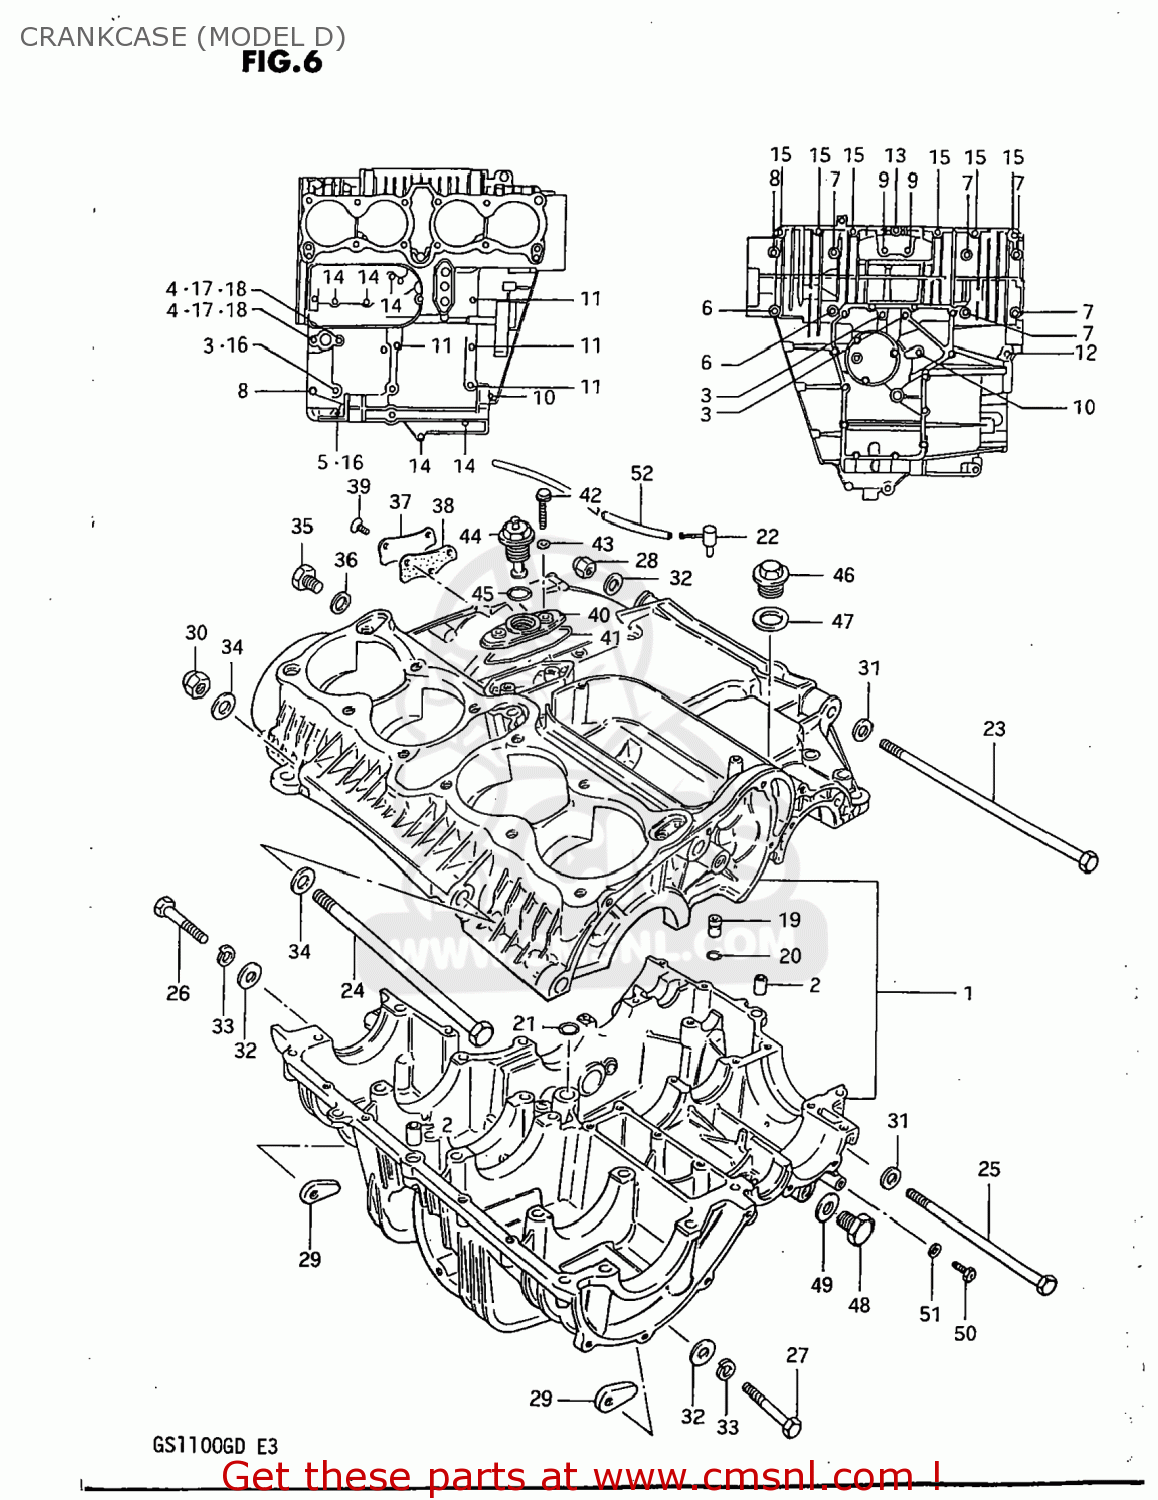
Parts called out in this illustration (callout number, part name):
1	CRANKCASE SET
2	PIN
3	BOLT
4	BOLT 8X110
5	BOLT
6	BOLT
7	BOLT (8X90)
8	BOLT (8X65)
9	BOLT 8X60
10	BOLT (6X90)
11	BOLT (6X75)
12	BOLT 6X55
13	BOLT 6X50
14	BOLT (6X45)
15	BOLT
16	NUT 8MM
17	NUT
18	GASKET 8.2X14X1 (NAS)
19	UNION
20	O RING(D:1.05,ID:3.1)
21	O RING(D:3.2,ID:12.9)
22	BPLUG,BEVEL GEAR BREATHER
23	BOLT
24	BOLT
25	BOLT
26	BOLT (10X60)
27	BOLT (10X50)
28	NUT (10MM)
29	NUT
30	NUT
31	WASHER (10.5X20X3.2)
32	WASHER
33	LOCK WASHER
34	WASHER
35	PLUG (14X12)
36	GASKET(14X19.2X2) (NAS)
37	CAP,OIL GALLERY
38	GASKET,OIL GALLERY (MCA)
39	SCREW
40	HOUSING,OIL PRESSURE SWITCH
41	O RING,PRESSURE SWITCH HOUSING
42	BOLT
43	WASHER
44	SWITCH ASSEMBLY
45	O RING(D:1.9,ID:18.8)
46	PLUG
47	GASKET
48	PLUG
49	GASKET(14X19.2X2) (NAS)
50	SCREW(6X10)
51	WASHER
52	HOSE
